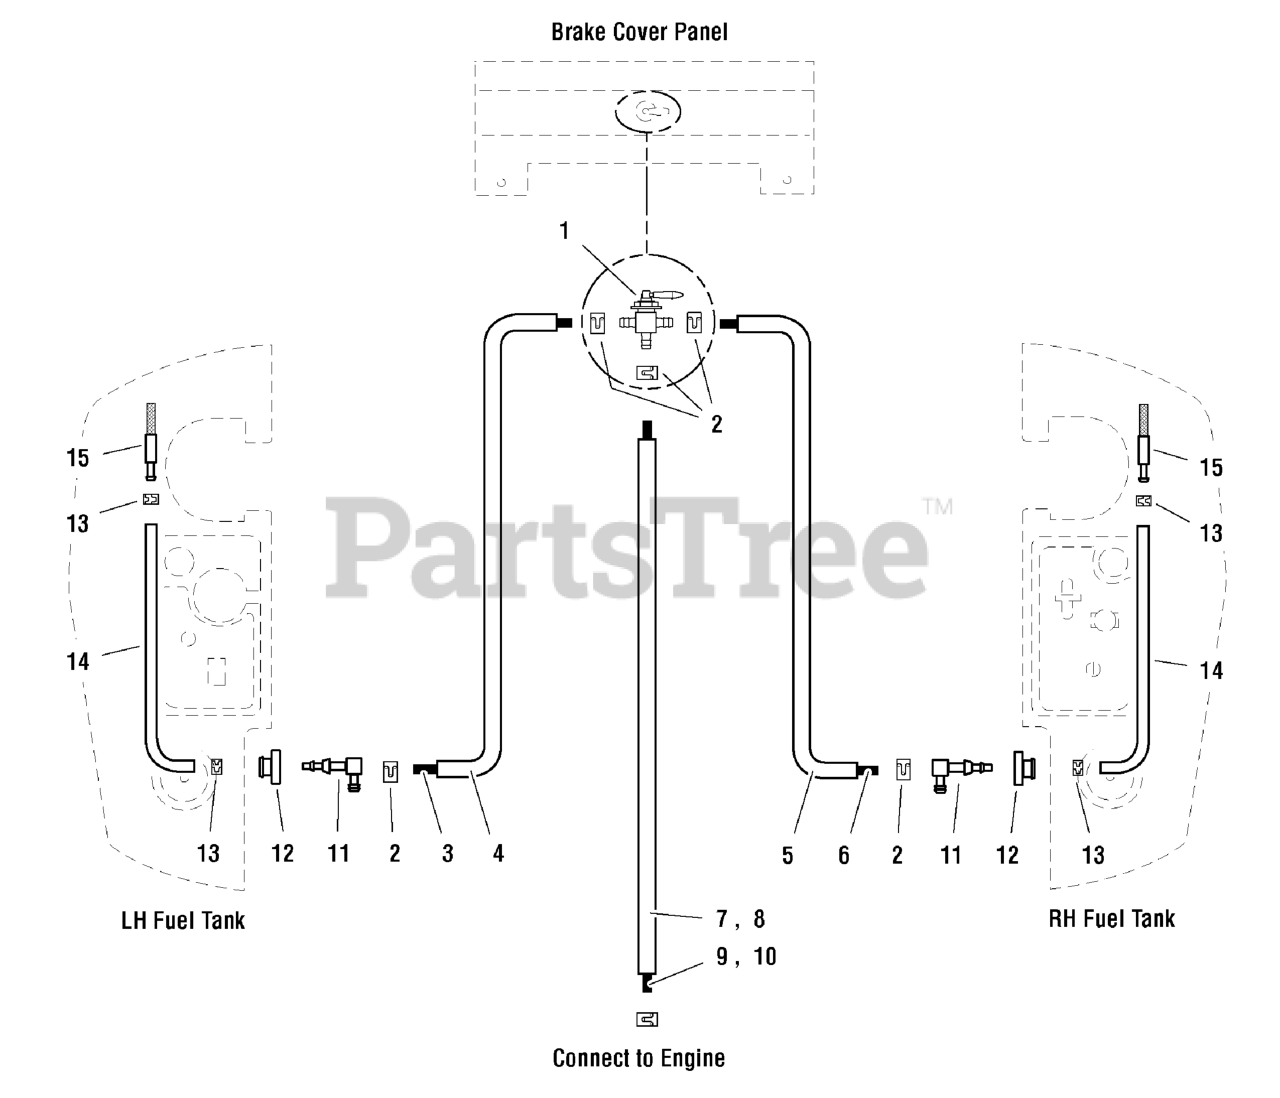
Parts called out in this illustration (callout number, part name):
1	VALVE, Fuel Shut Off
2	CLAMP, Hose
3	1/4" Fuel Line, 60" Long
4	WIRE LOOM, 58"
5	WIRE LOOM, 50"
6	1/4" Fuel Line, 52" Long
7	WIRE LOOM, 38"
8	WIRE LOOM, 51"
9	1/4" Fuel Line, 40" Long
10	1/4" Fuel Line, 53" Long
14	ASSM, FUEL HOSE, 20"
